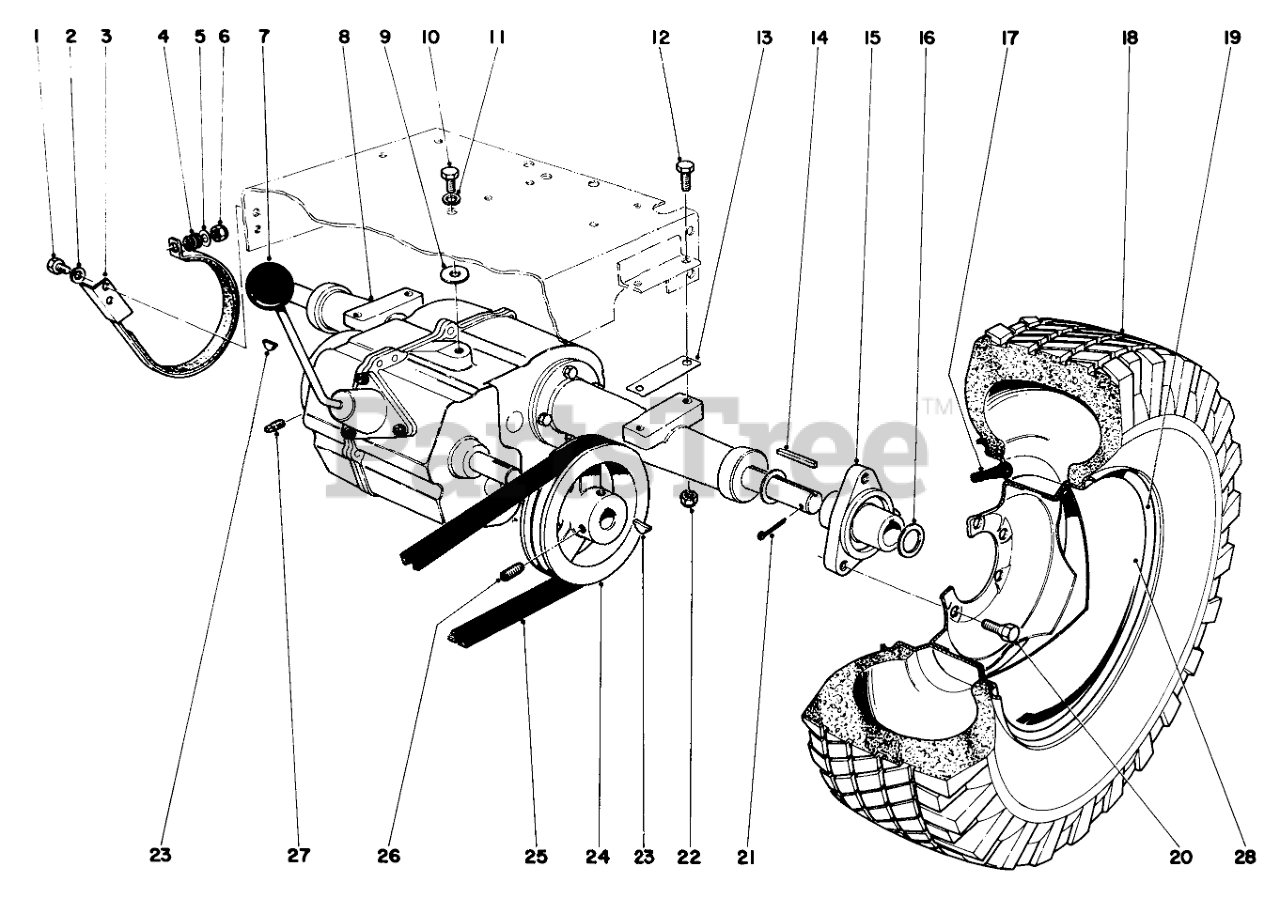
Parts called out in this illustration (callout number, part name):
1	SCREW-HH
2	WASHER-LOCK
3	Brake Band Assy.
4	Spring
5	WASHER-FLAT
6	Nut
8	Transmission Complete
9	WASHER-FLAT
10	SCREW-HH
11	WASHER-LOCK
12	SCREW-HH
13	Axle Pad
14	KEY-SQUARE
15	Wheel Hub
16	Washer
17	STEM-VALVE
18	Tire
19	Rear Wheel
20	Tapered Capscrew
21	PIN-COTTER
23	KEY-WOODRUFF
24	Pulley Transmission
25	V-BELT, TRANS (SET OF 2)
26	SCREW-SET
27	Set Screw
28	Hub Cap 960
